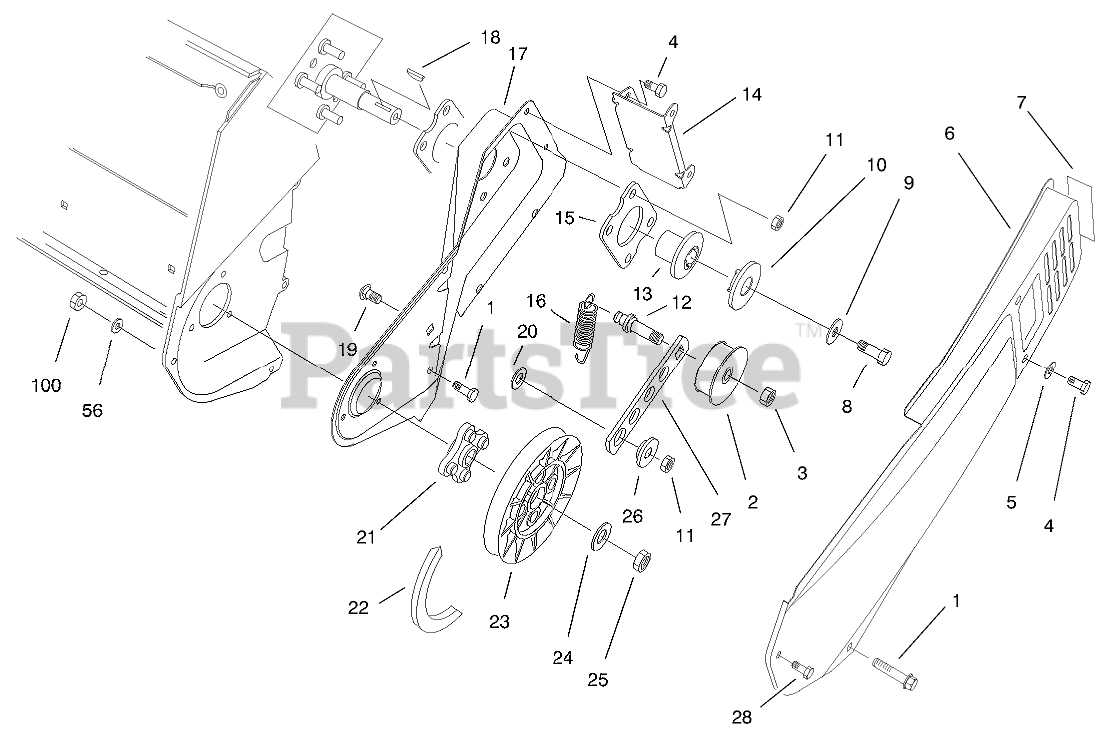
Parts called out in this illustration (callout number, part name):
1	SCREW-PLASTIC
2	PULLEY-IDLER
3	NUT-LOCK, NI
4	SCREW-HWH
5	WASHER-FLAT
6	Cover-Belt
7	Decal
8	SCREW-HH
9	WASHER-FLAT
10	CAP-HALF SHEAVE
11	NUT-LOCK, NI
12	PIN-IDLER
13	Hub-HALF SHEAVE
14	Bracket-Cover
15	Plate Engine
16	SPRING-EXTENSION
17	Sideplate-LH
18	KEY-WOODRUFF
19	SCREW-CARR
20	WASHER
22	V-BELT
23	PULLEY-DRIVEN
24	WASHER-FLAT
25	NUT-LOCK, NI
26	BUSHING-IDLER
27	ARM-IDLER
56	WASHER-FLAT
100	NUT-LOCK, NI
